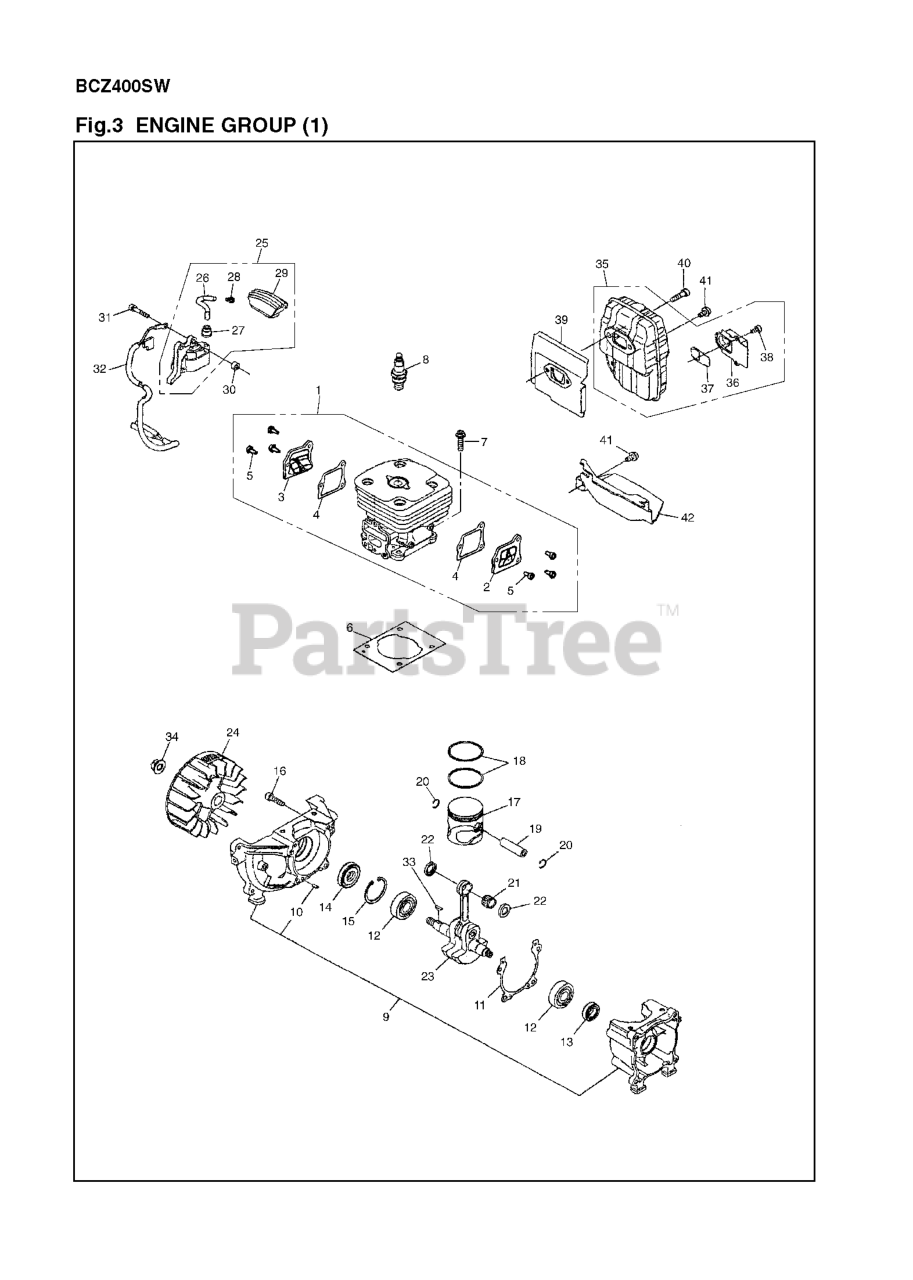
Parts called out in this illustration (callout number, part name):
1	CYLINDER ASSY
2	COVER TRS STARTER SIDE
3	COVER,TRF FLYWHEEL SIDE
4	GASKET TR
5	BOLT
6	GASKET TR
7	BOLT
8	SPARK PLUG CMR7H-10
9	CRANKCASE ASSY
10	PIN
12	BEARING
16	BOLT M5X20 T27
18	RING PISTON
21	ROLLER BEARING
22	WASHER
23	CRANK SHAFT ASSY
24	ROTOR
25	COIL ASSY
27	CAP
30	SPACER
31	BOLT M4 X 25
32	CORD ASSY
33	KEY
34	NUT
35	MUFFLER ASSY
37	ARRESTER
40	BOLT M5X20 T27
41	BOLT (RPLS T495051010-11)
